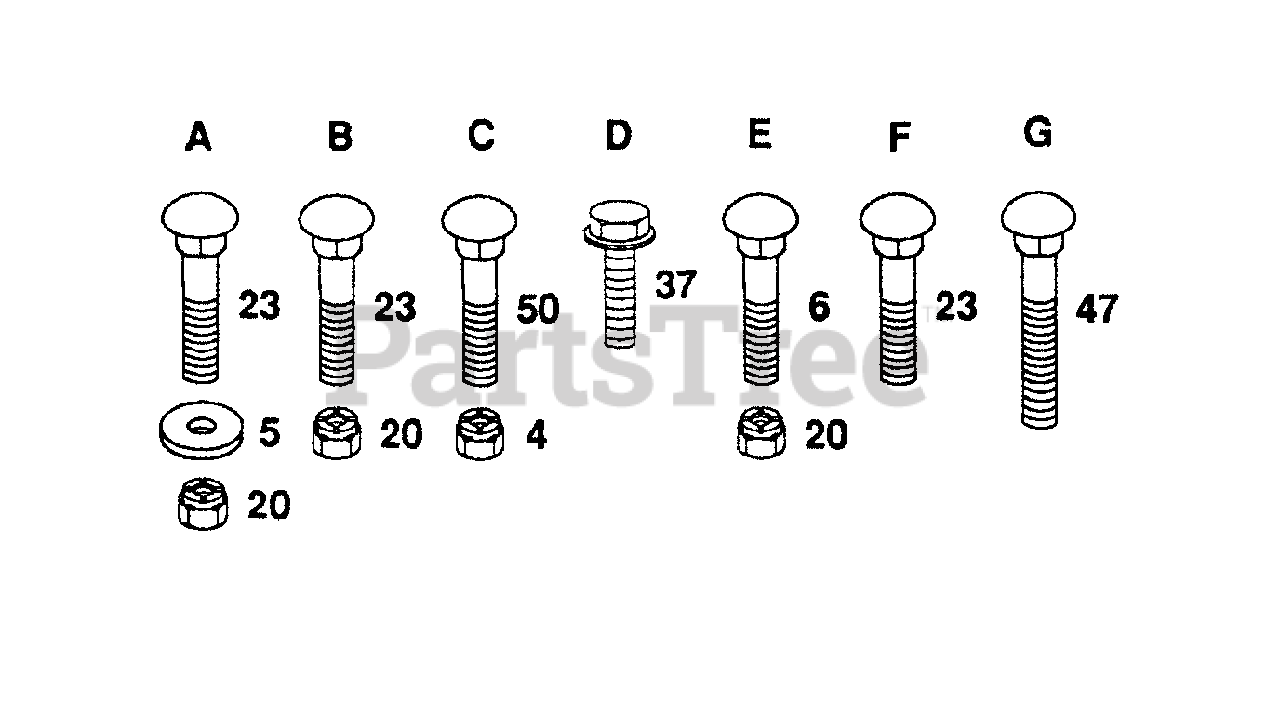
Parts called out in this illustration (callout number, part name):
4	Nut, Crownlock 3/8 - 16
5	Washer 11/32 x 3/4 x 16 Gauge
6	Bolt, Carriage 5/16 - 18 x 5/8
20	Nut, Crownlock 5/16 - 18
23	Bolt, Carriage 5/16 - 18 x 3/4
37	Screw, Hex, Washer Head 3/8 - 16 x 1-1/4
47	Bolt, Carriage 3/8 - 16 x 1-1/4
50	Bolt, Carriage 3/8 - 16 x 3/4
